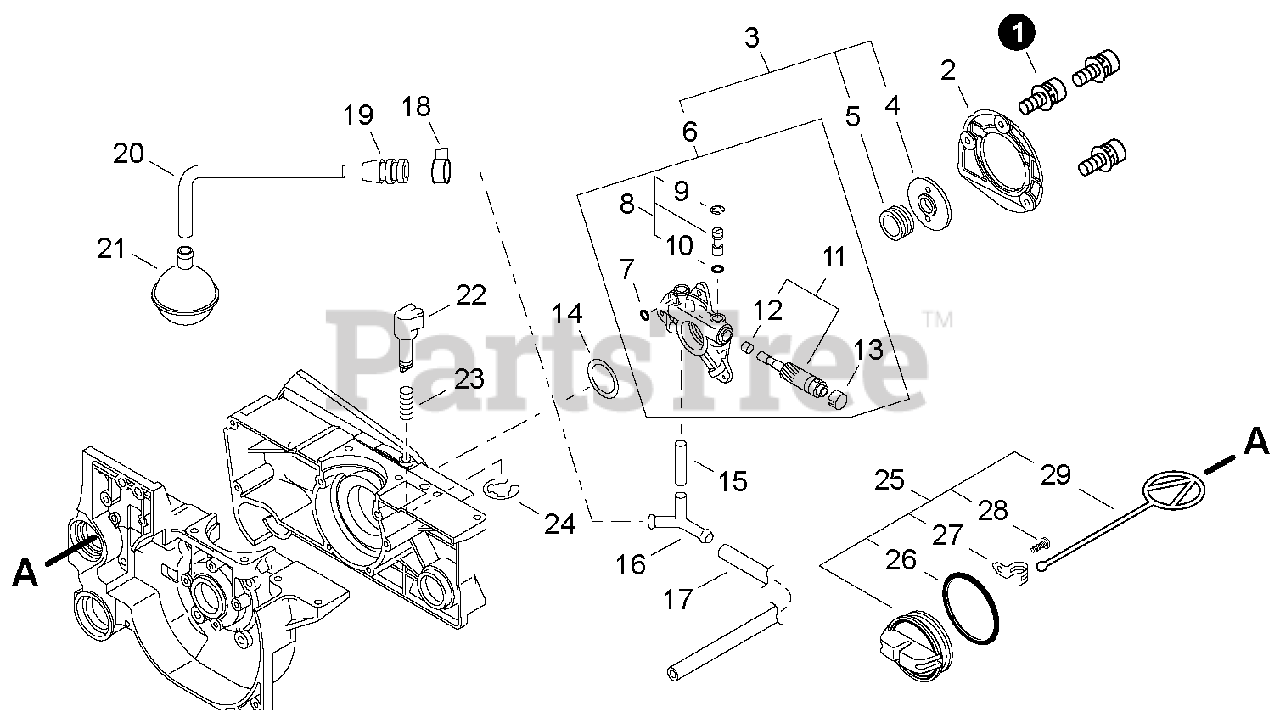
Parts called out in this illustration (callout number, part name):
1	BOLT 4×12
2	COVER, OIL PUMP - ORANGE
3	AUTO-OILER KIT
4	WASHER 12
5	GEAR, WORM
6	AUTO-OILER ASSY
7	O-RING 3
8	PIN ASSY, CONTROL
11	PLUNGER KIT
13	CAP, PLUNGER
15	PIPE, OIL 3×6×20
16	CONNECTOR, PIPE
17	PIPE, FUEL 3×6×200
18	CLIP Ø6.5 MM
20	PIPE, OIL
21	FILTER, OIL
24	E-RING 3
25	CAP ASSY, OIL
27	RETAINER, CONNECTOR
28	SCREW, TAPPING 3×8
29	CONNECTOR, CAP L= 60 MM
